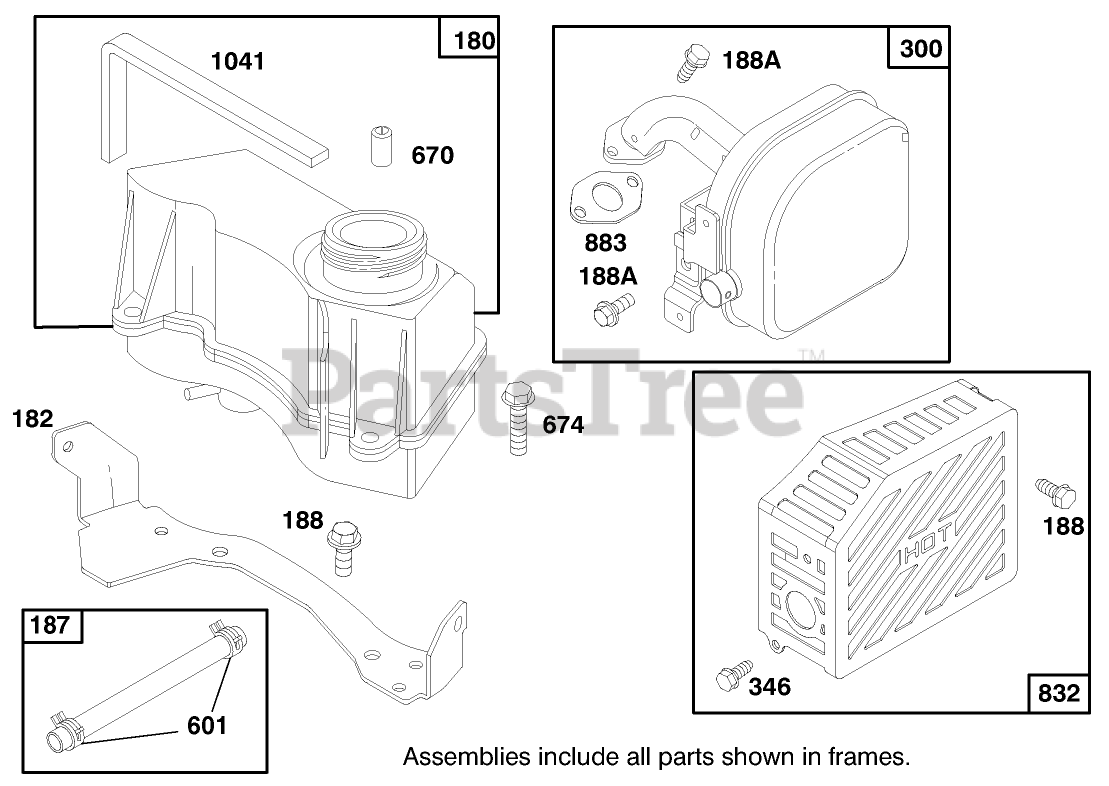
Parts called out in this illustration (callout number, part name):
187	BRIGGS 296004
188A	SCREW - HEX HEAD
300	MUFFLER - EXHAUST
346	SCREW - SELF-TAPPING
670	SPACER
674	SCREW - HEX HEAD
